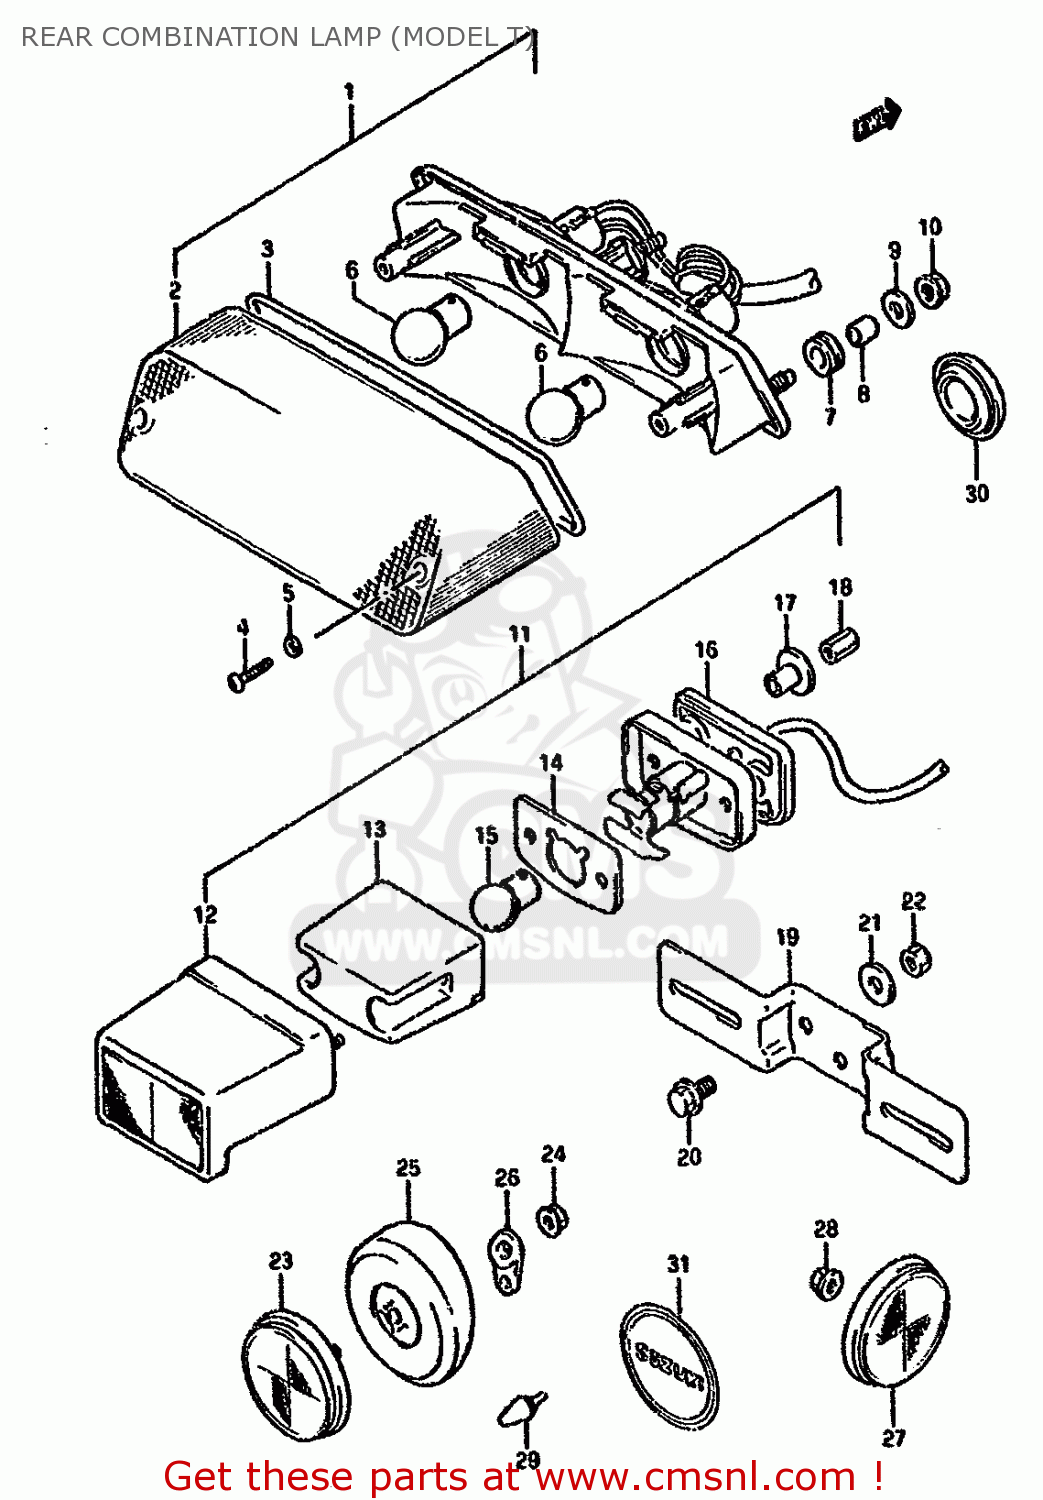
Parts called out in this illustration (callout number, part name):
1	LAMP ASSY,RR COMBINATION
2	LENS
3	GASKET (NAS)
4	SCREW
5	GASKET (NAS)
6	BULB(12V21/5W)
7	CUSHION
8	SPACER (6.1X8X9.5)
9	WASHER(6.5X18X1)
10	NUT
11	LAMP ASSY, LICENSE
12	COVER, LENS
13	LENS
14	GASKET,LICENSE LAMP (NAS)
15	BULB(12V5W,BF150-40160A)
16	CUSHION
17	SPACER
18	NUT
19	BRACKET,LICENSE PLATE
20	BOLT
21	WASHER(6.5X20X1.6)
22	NUT 6MM
23	REFLECTOR ASSY,RR
24	NUT
25	SPACER, REAR REFLECTOR
26	WASHER,RR REFLECTOR
27	REFLEX REFLECTOR
28	NUT
29	CUSHION
30	CAP OD:40
31	EMBLEM, REAR
